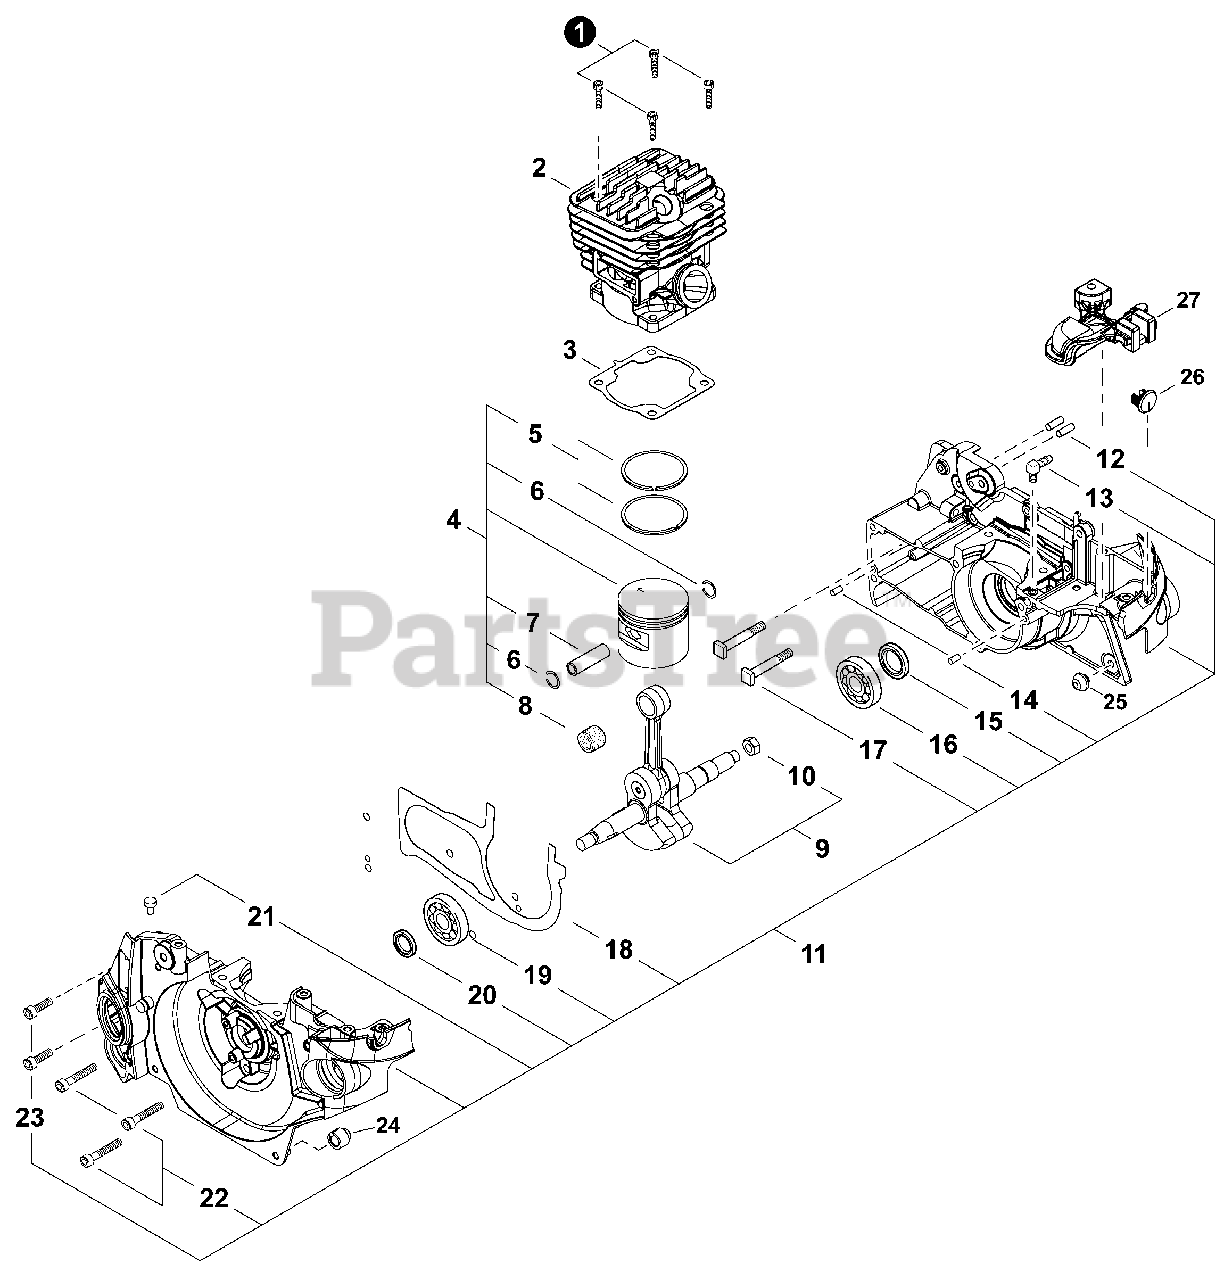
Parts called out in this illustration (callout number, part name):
1	BOLT M5×18
2	CYLINDER
3	GASKET, CYLINDER
4	PISTON KIT
5	RING, PISTON
6	RING, SNAP
7	PIN, PISTON 11
8	BEARING, NEEDLE 11
9	CRANKSHAFT ASSY
10	NUT M8
11	CRANKCASE ASSY
12	PIN, LOCATING Ø4×11
13	CONNECTOR, PIPE
14	PIN, LOCATING Ø4×8
15	SEAL, OIL 15
16	BEARING, BALL 6202 C3
17	BOLT, STUD 8
18	GASKET, CRANKCASE
19	BEARING, BALL 6201 C3
20	SEAL, OIL 12
21	VENT ASSY
22	BOLT M5×35
23	BOLT M5×18
24	CUSHION M
25	CUSHION C
27	COVER, DUST
